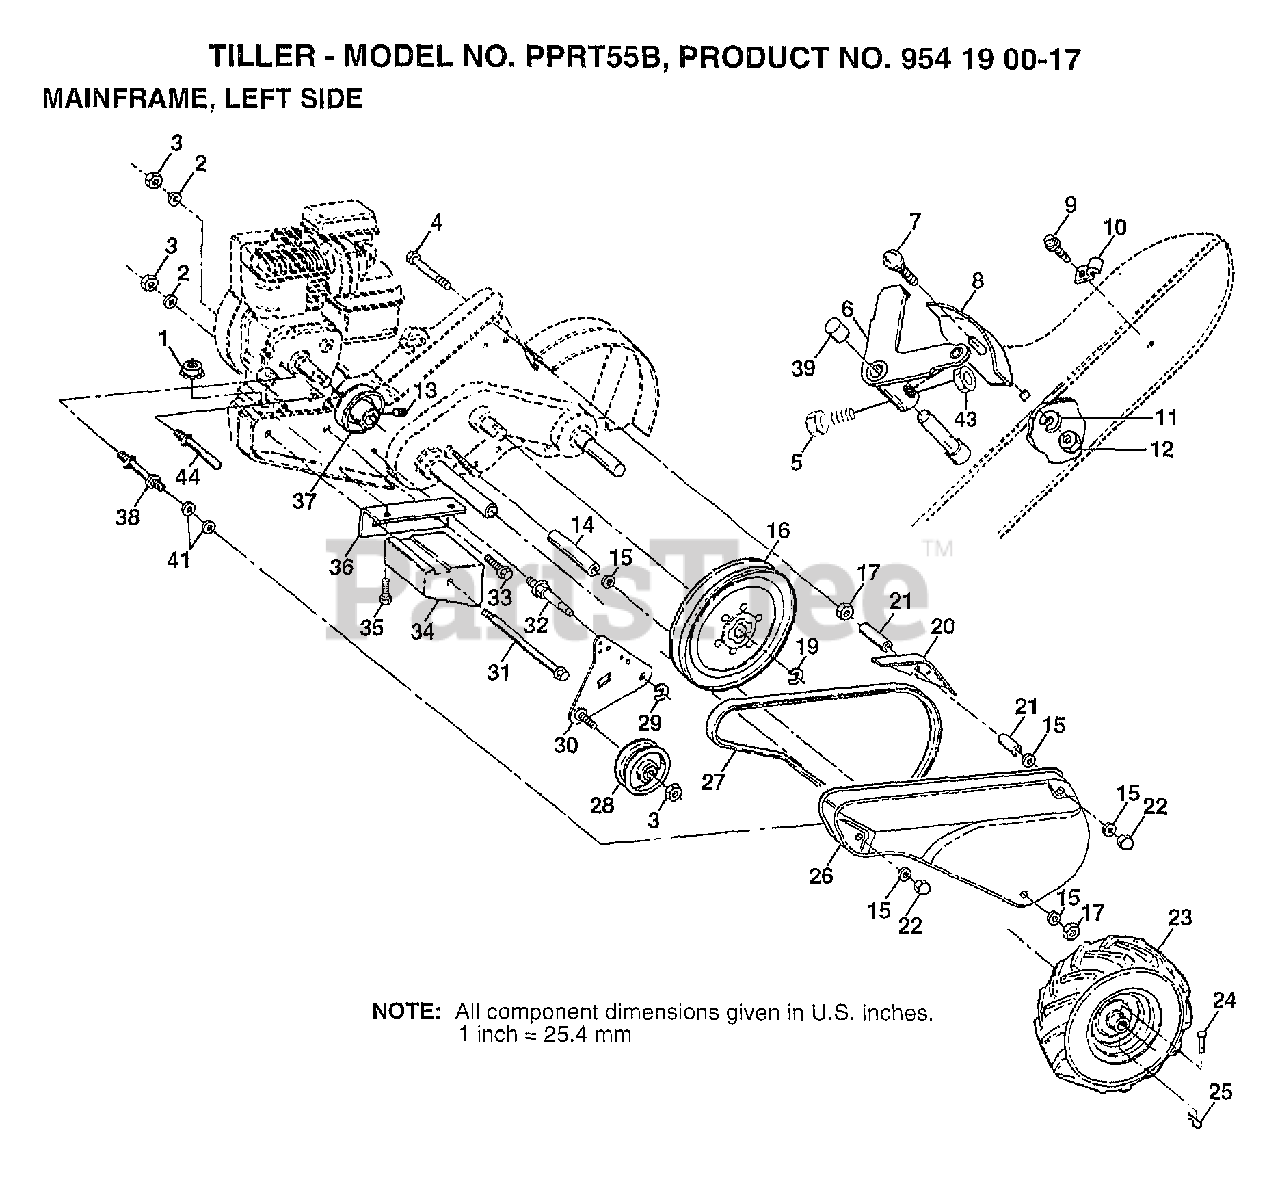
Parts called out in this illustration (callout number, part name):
2	LOCKWASHER
3	NUT.HEX.3/8-16UNC
4	BOLT TI
5	"SCREW-LEVER,SHI"
6	LEVER ASM CRT
7	BOLT
8	PANEL TI
10	CONDIUT CLIP T
11	LOCKWASHER
13	SET SCREW
14	SPACER
15	WASHER
16	SHEAVE.TRANS.
17	NUT.HEX.5/16-18
20	GUARD CRT
21	SPACER.SPLIT
22	NUT TI
23	TIRE TI
24	RIVET DRILLED
25	RETAINER M
27	BELT-V
28	PULLEY-IDLER TI
29	KLIP RING
30	BRACKET ASM IDLER
31	BOLT CRT
32	SHIFT ARM CRT
33	BOLT
34	COUNTERWEIGHT CRT
35	BOLT
36	BRACKET LH CRT
37	ENGINE PULLEY
38	STUD.GUARD.BELT
39	CAP PLUNGER BLACK
41	WASHER
43	LOCKNUT
44	KEEPER.BELT.ENGINE
